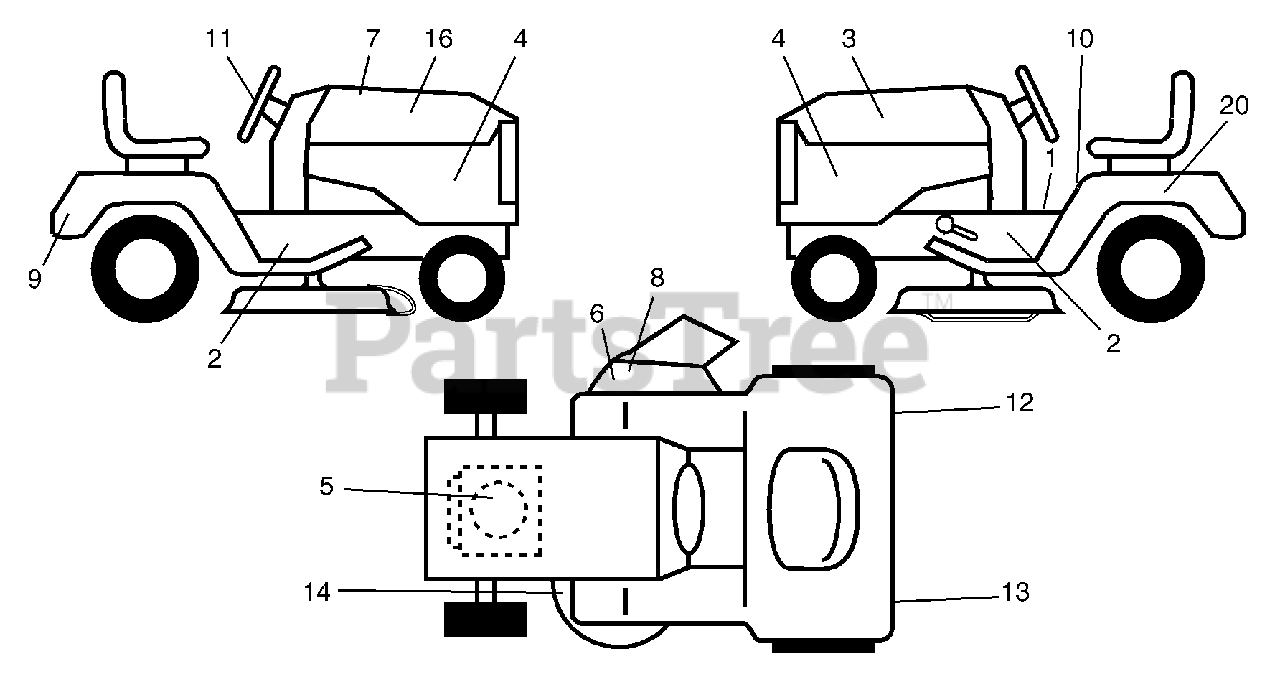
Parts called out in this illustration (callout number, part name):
1	Decal Oper
2	Decal Chassis
3	Decal Hood LH
4	Decal Side Panel Logo
5	Decal HP Engine
6	Decal Warning, Keep Hand Away
7	Decal Replacement Parts
8	Decal Deck "B" 42"
9	Decal Fender Logo
10	Decal Fender Danger
11	Decal Ins Strg Whl
12	Decal Fend Reflector Rh
13	Decal Fend Reflector Lh
14	Decal V-Belt Schematic
16	Decal Hood Rh
20	Decal Bat Dan/Psn
